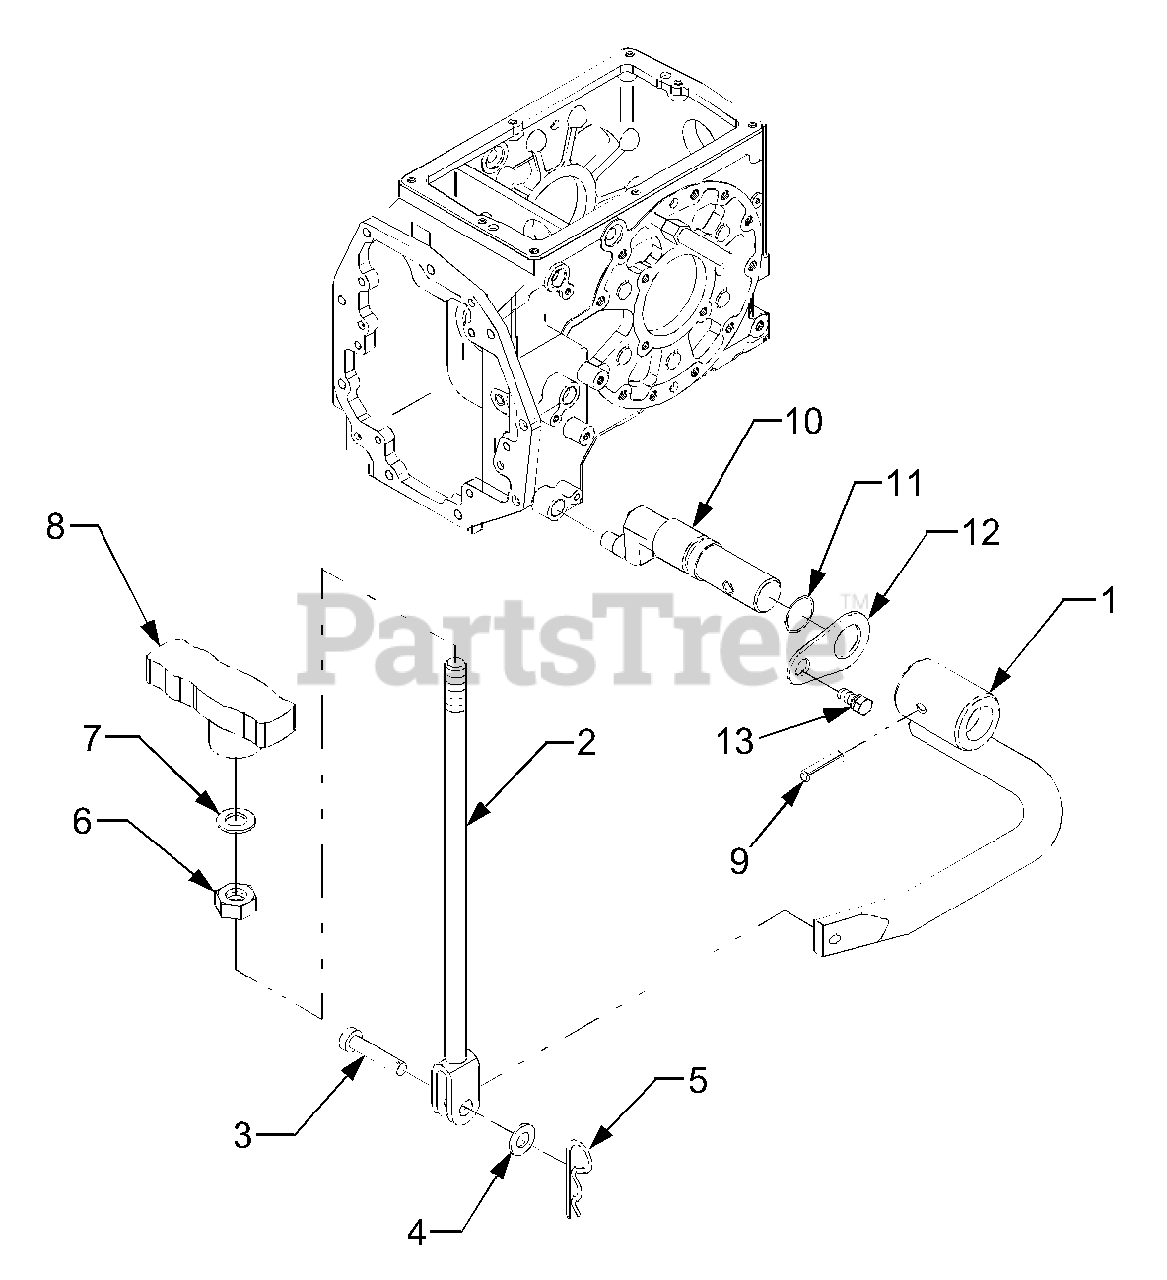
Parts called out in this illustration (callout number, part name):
1	Lever 1, Front Wheel
2	Lever 2, Front Wheel
4	Washer, Plain
7	Washer, Plain
8	Grip
10	Arm, Shift (Front Wheel Drive)
